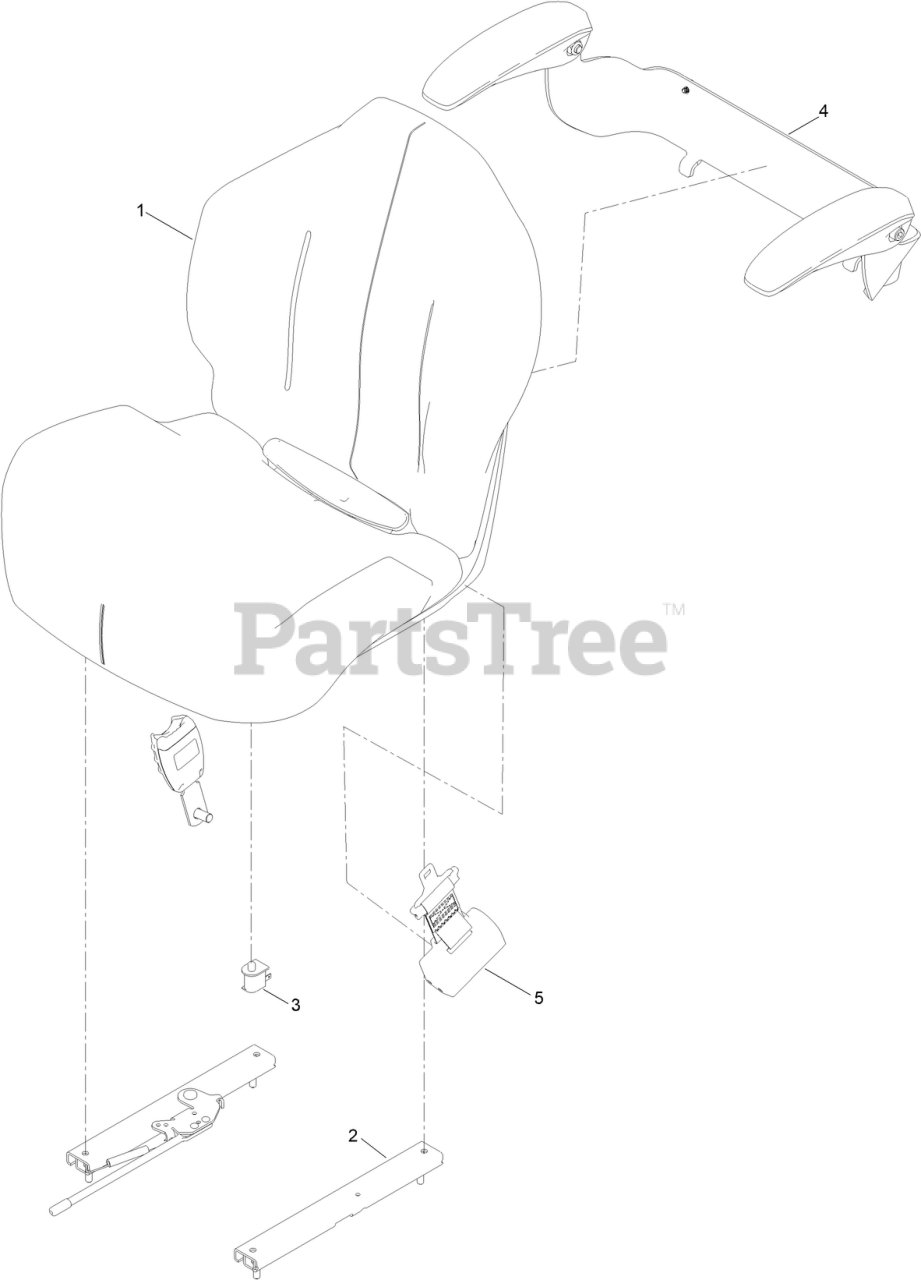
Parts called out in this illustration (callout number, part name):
1	SEAT ASM
2	KIT-ADJUSTER
3	SWITCH-BAIL
4	KIT-ARM REST
5	SEAT BELT KIT
